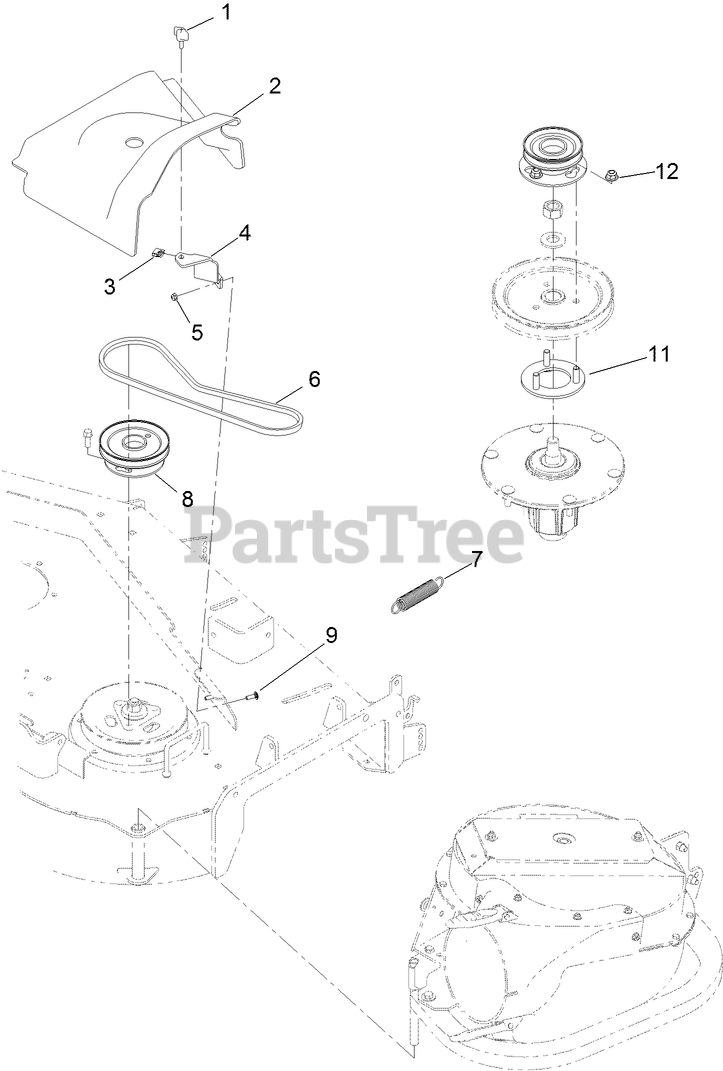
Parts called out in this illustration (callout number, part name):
2	BELT COVER
3	NUT-SPEED
4	BRACKET-COVER, BELT
5	NUT-HF
6	BELT-V
7	SPRING-EXTENSION
8	PULLEY-BLOWER
9	BOLT-CARR
11	PULLEY MOUNT ASM
12	NUT-HF, NI
